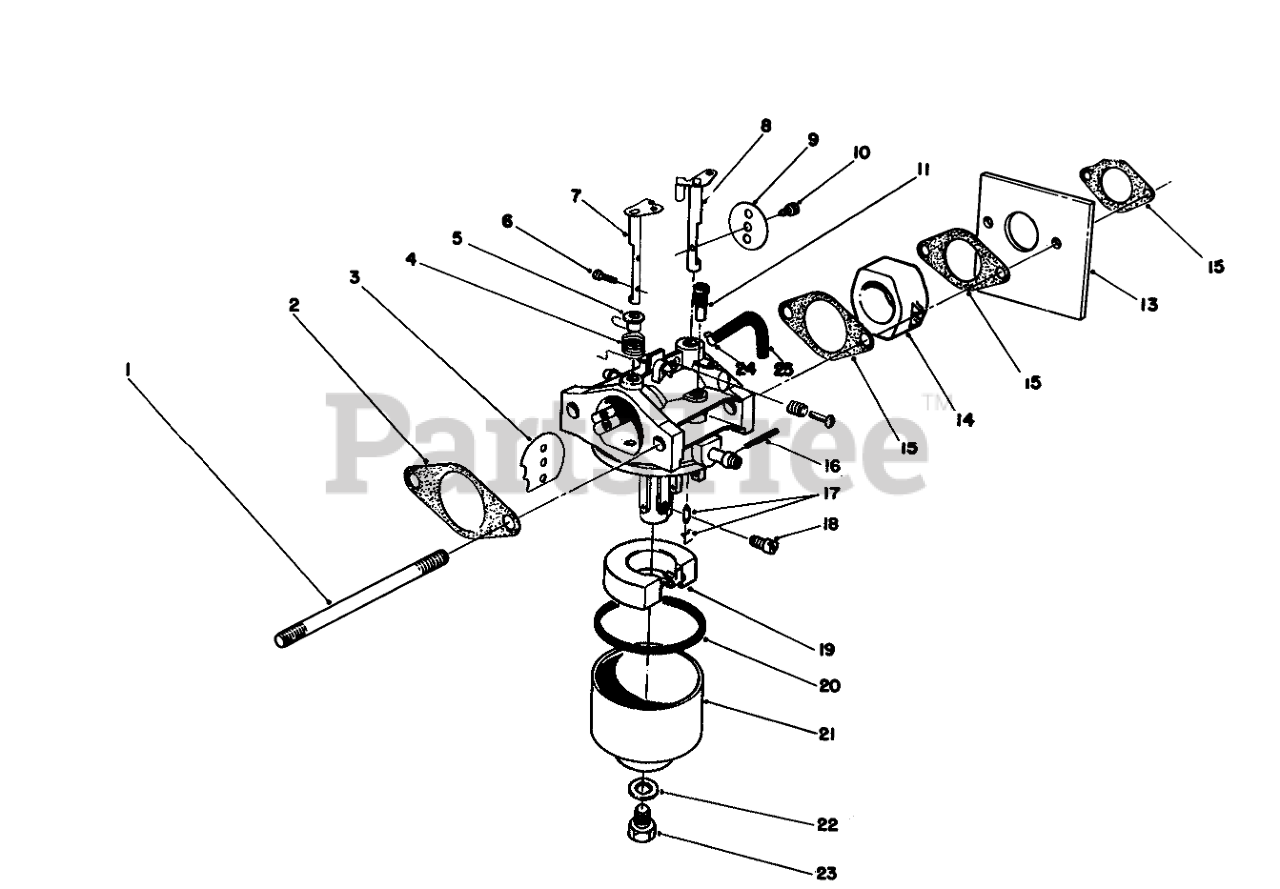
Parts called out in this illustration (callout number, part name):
1	STUD-CARBURETOR
2	GASKET-AIR CLEANER
3	PLATE
4	SPRING
5	BUSHING
6	SCREW
7	SHAFT-CHOKE
8	SHAFT
9	PLATE
10	Screw-Throttle
11	PILOT JET
13	SHIELD-CARBURETOR
14	INSULATOR-CARBURETOR
15	GASKET-CARB
16	Pin
17	NEEDLE
18	JET-MAIN
19	FLOAT
20	GASKET
21	BOWL - FLOAT
22	GASKET
23	SCREW
24	CLAMP
25	VENT TUBE
